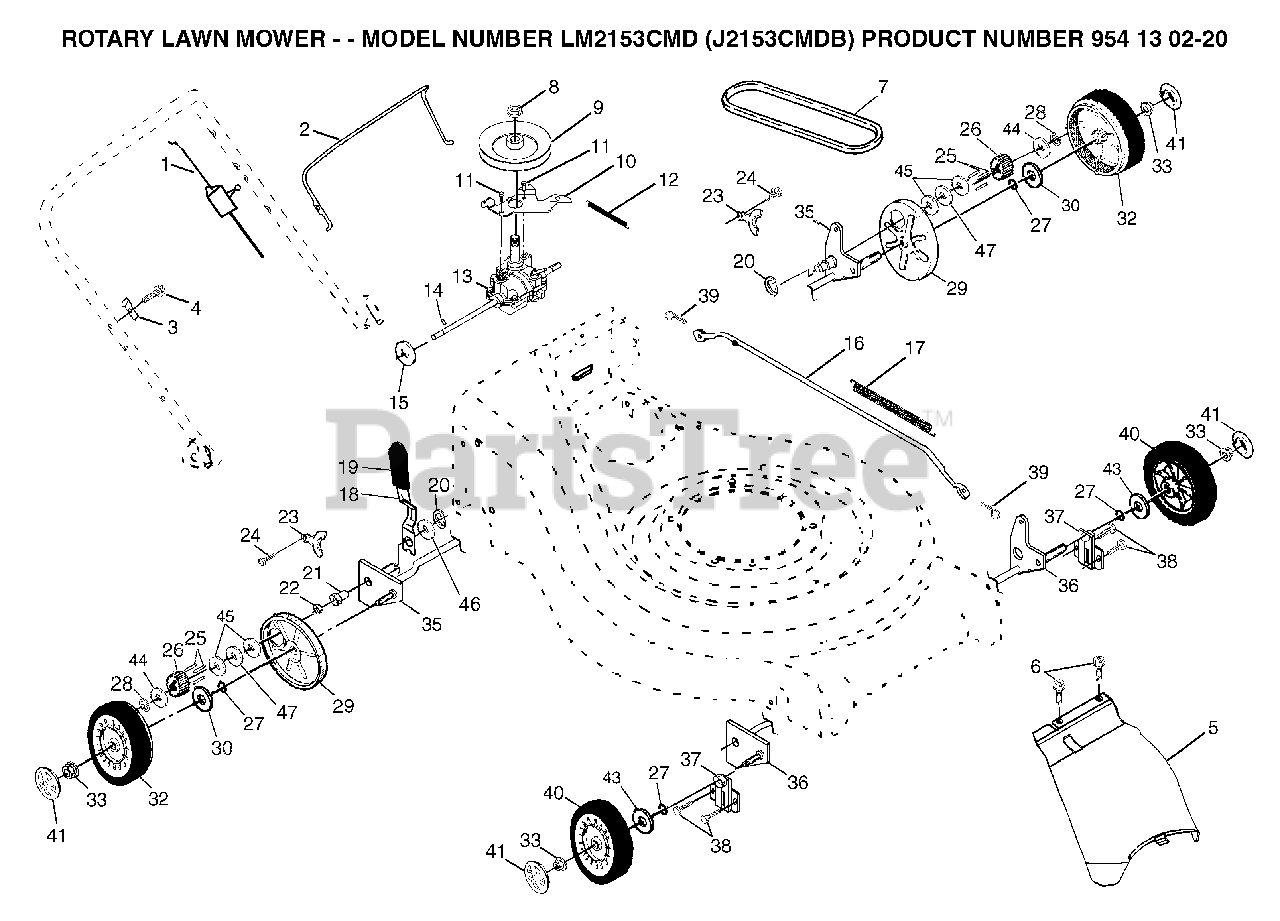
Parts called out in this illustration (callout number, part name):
1	DRIVE CABLE
2	BAIL.CONT.DR.21.RWGD.BLACK
3	DOWNSTOP BRACKET
5	DRIVE COVER
8	FLANGED LOCKNUT 3/8-16 ZINC
13	TRANSMISSION ASM. (WALK)
14	PIN.SPRING.THRUST
15	THRUST WASHER
16	ROD CONNECTING
17	SPRING
18	SPRING
19	KNOB
21	RP BEARING SUPPORT
22	BEARING, BALL
23	BRACKET
26	DRIVE PINION
27	O-RING
28	E-RING 7/16 RE
29	DUST COVER, WHEEL
30	WASHER FLUT
32	WHEEL, 9 X 2
33	HEX FLANGE LOCKNT
35	SHAFT ASSY
36	SHAFT ASSY
37	RETAINER.FRONT.SHAFT
39	RETAINER CLIP
40	WHEEL ASMBLY FRONT
41	CAP.HUB.ARC.SPOKE.8".LP
43	WASHER PM
44	WASHER
45	BELLEVILLE WASHER
